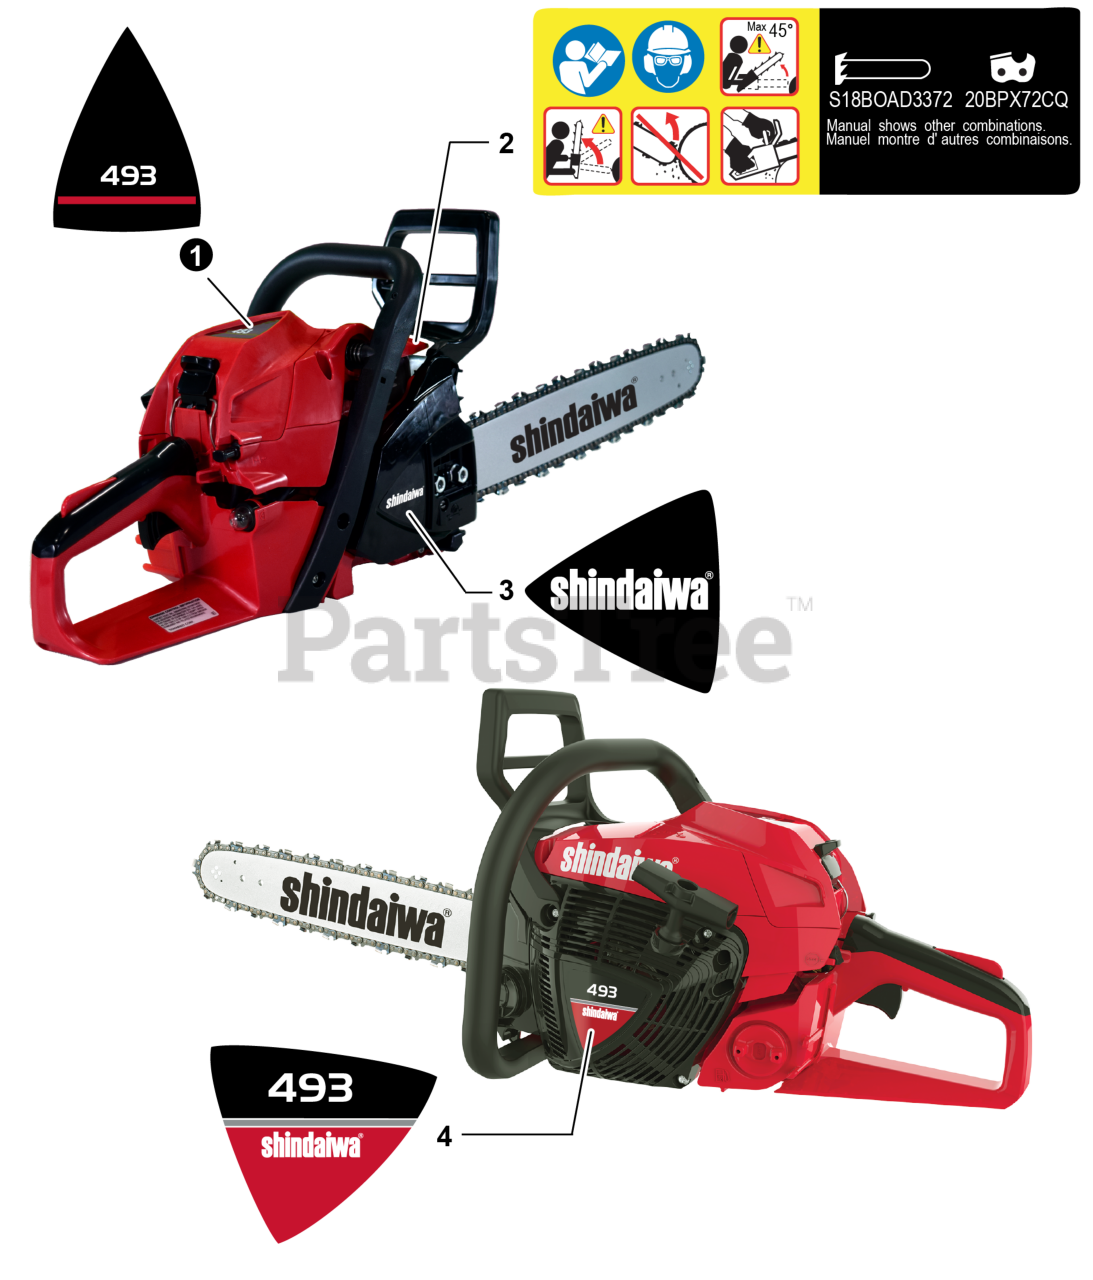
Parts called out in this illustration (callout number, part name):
1	LABEL - MODEL 493
2	LABEL - CAUTION
3	LABEL - SHINDAIWA
4	LABEL - RECOIL STARTER - 493
